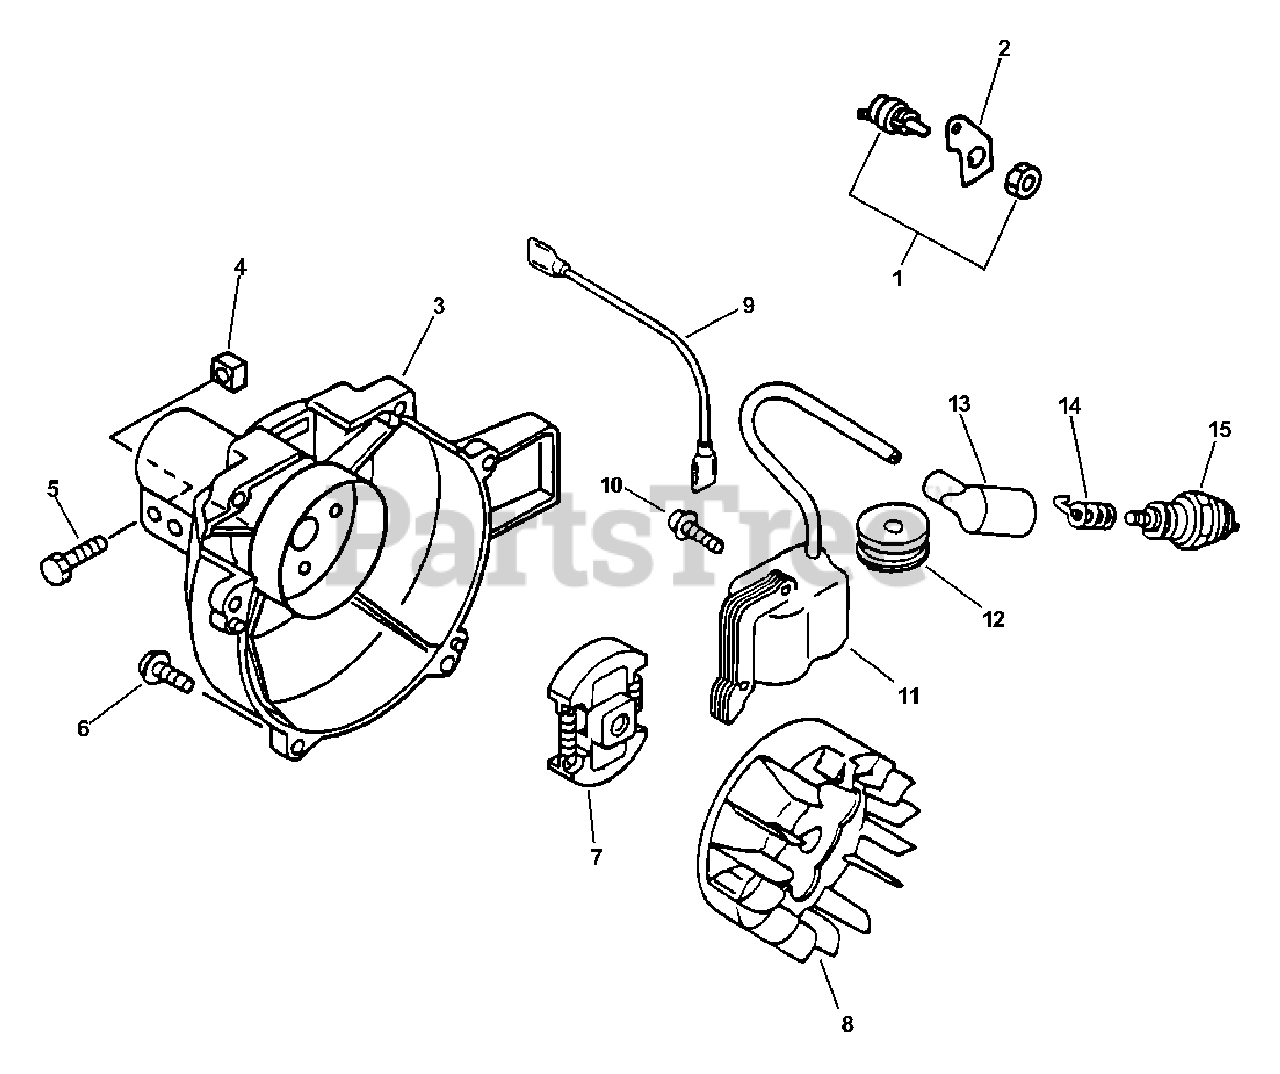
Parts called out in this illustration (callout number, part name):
1	SWITCH, ON-OFF
2	BRACKET, SWITCH
3	FAN CASE ASSY
4	NUT - 5 -- SQUARE
5	BOLT 5×28
6	BOLT 4×18
7	CLUTCH ASSY
8	FLYWHEEL
9	LEAD
10	SCREW 4×22
11	COIL, IGNITION
13	CAP, SPARK PLUG
14	TERMINAL, SPARK PLUG
15	SPARK PLUG - BPM7A
15	SPARK PLUG - RCJ7Y
